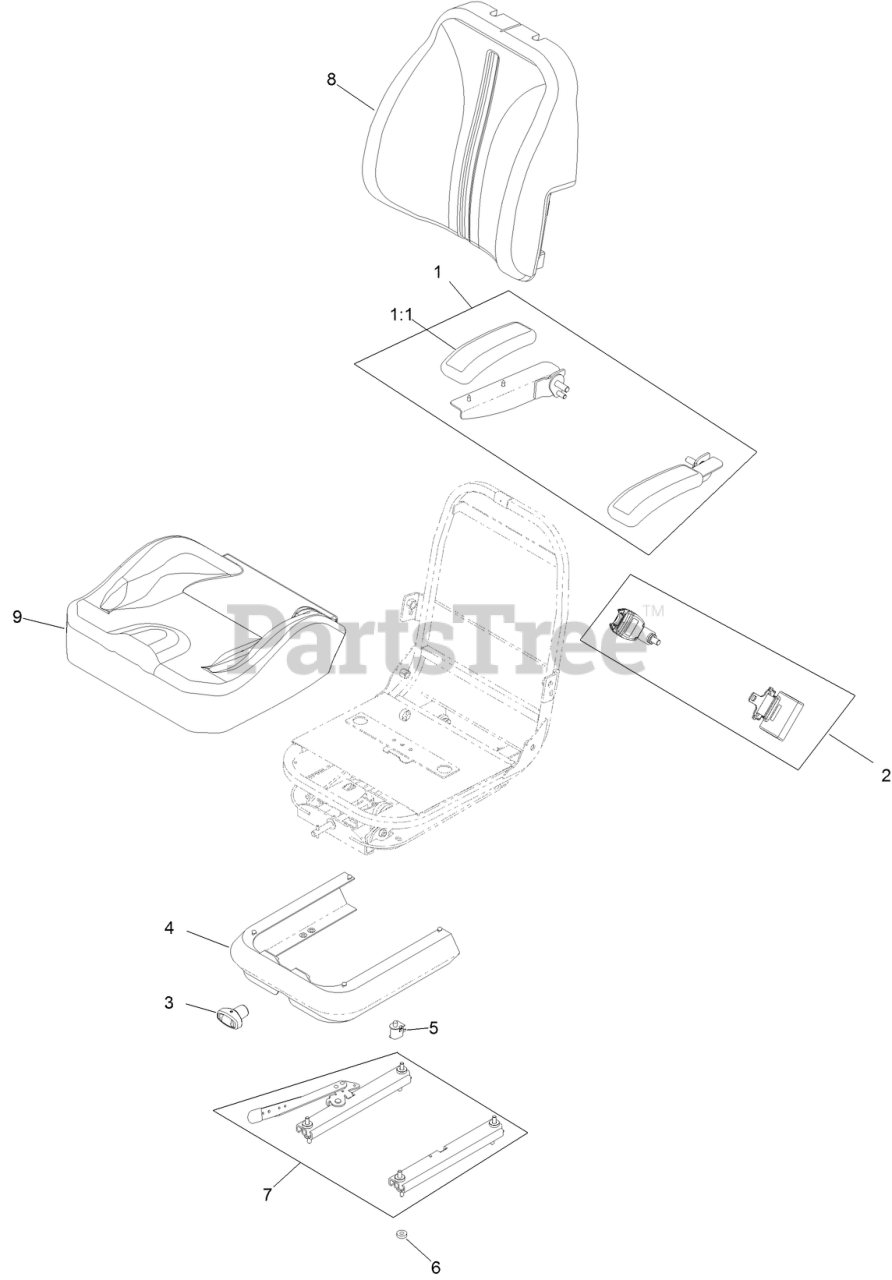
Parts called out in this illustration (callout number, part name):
1	ARMREST KIT
1:1	CUSHION-REST, ARM
2	SEAT BELT KIT
3	KNOB-ADJUSTER
4	COVER-SKIRT W/FASTENERS
5	SWITCH-BAIL
7	TRACK ASM
8	COVER-BACK, SUSP SEAT
9	COVER-BOTTOM, SUSP SEAT
